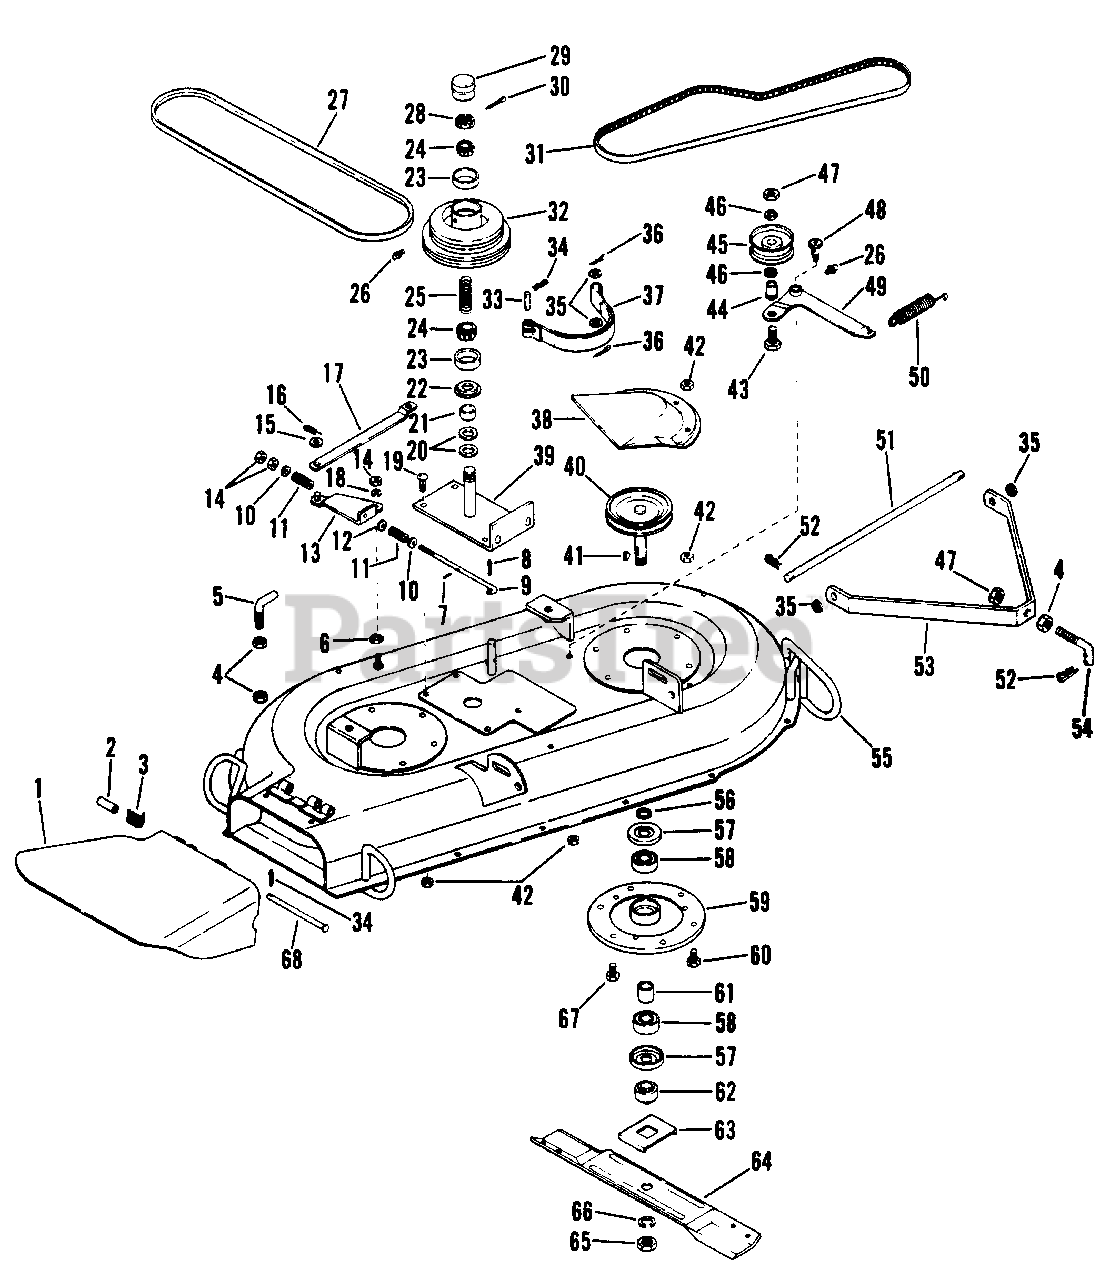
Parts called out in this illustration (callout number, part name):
1	CHUTE, DEFLECTOR
2	BUSHING
3	SPRING, TORSION
4	NUT, JAM 1/2-13 HEX
5	HOOK, HANGER
6	SPACER
7	PIN, SPRING .125X.750
8	PIN, COTTER .06X.50
9	ROD, BRAKE
10	WASHER, FLAT .312X.734X.065
11	SPRING
12	WASHER, FLAT .406X.812X.065
13	LEVER, BRAKE
14	NUT, HEX 5/16-18
15	WASHER, FLAT .406X.812X.065
16	HAIR PIN, INTERNAL
17	LINK
18	WASHER, LOCK 5/16 SP
19	BOLT, CARRIAGE 3/8-16X.75
20	WASHER, FLAT .813X1.37X.100
21	SPACER
22	SEAL
23	CUP, BEARING
24	CONE, BEARING
25	SPRING, COMPRESSION
26	FITTING, LUBE 1/4-28
27	BELT, MOWER
28	NUT, SLOTTED JAM
29	CAP
30	PIN, COTTER .125X1.25
31	BELT
32	SHEAVE
33	PIN
34	PIN, COTTER .09X.75
35	WASHER, FLAT .531X1.062X.095
36	PIN, COTTER .09X1.00
37	BAND, BRAKE
38	COVER
39	PLATE, DRIVE
40	SHEAVE, 3.75
40	SHEAVE, 4.00
41	KEY, WOODRUFF .187X.75 #9
42	NUT, LOCK 3/8-16
43	BOLT, HEX 1/2-13X1.25
44	BUSHING, FLANGE
45	PULLEY, IDLER
46	WASHER, FLAT .52X.81X.033
47	NUT, LOCK 1/2-13
48	BOLT, SHOULDER
49	ARM, IDLER
50	SPRING, DRIVE
51	PIN, TOW
52	HAIR PIN, INTERNAL
53	STRAP, MOWER
54	HOOK, TOW
56	WASHER, FLAT .812X1.496X.134
57	SLINGER, BEARING
58	BEARING, RADIAL
59	HOUSING, SPINDLE
60	BOLT, HEX 3/8-16X.75
61	SPACER
62	HUB, RETAINER
63	TRAY, BLADE
64	BLADE, MOWER
65	NUT, JAM 3/4-10 HEX
66	WASHER, LOCK 3/4 HEAVY
67	BOLT, HEX 3/8-16X1.00
68	PIN, HINGE
NS	DECAL, DANGER FOOT
NS	DECAL, NO STEP
NS	DECAL, CAUTION
NS	DECAL, WARNING EYE
NS	DECAL, DANGER HAND
